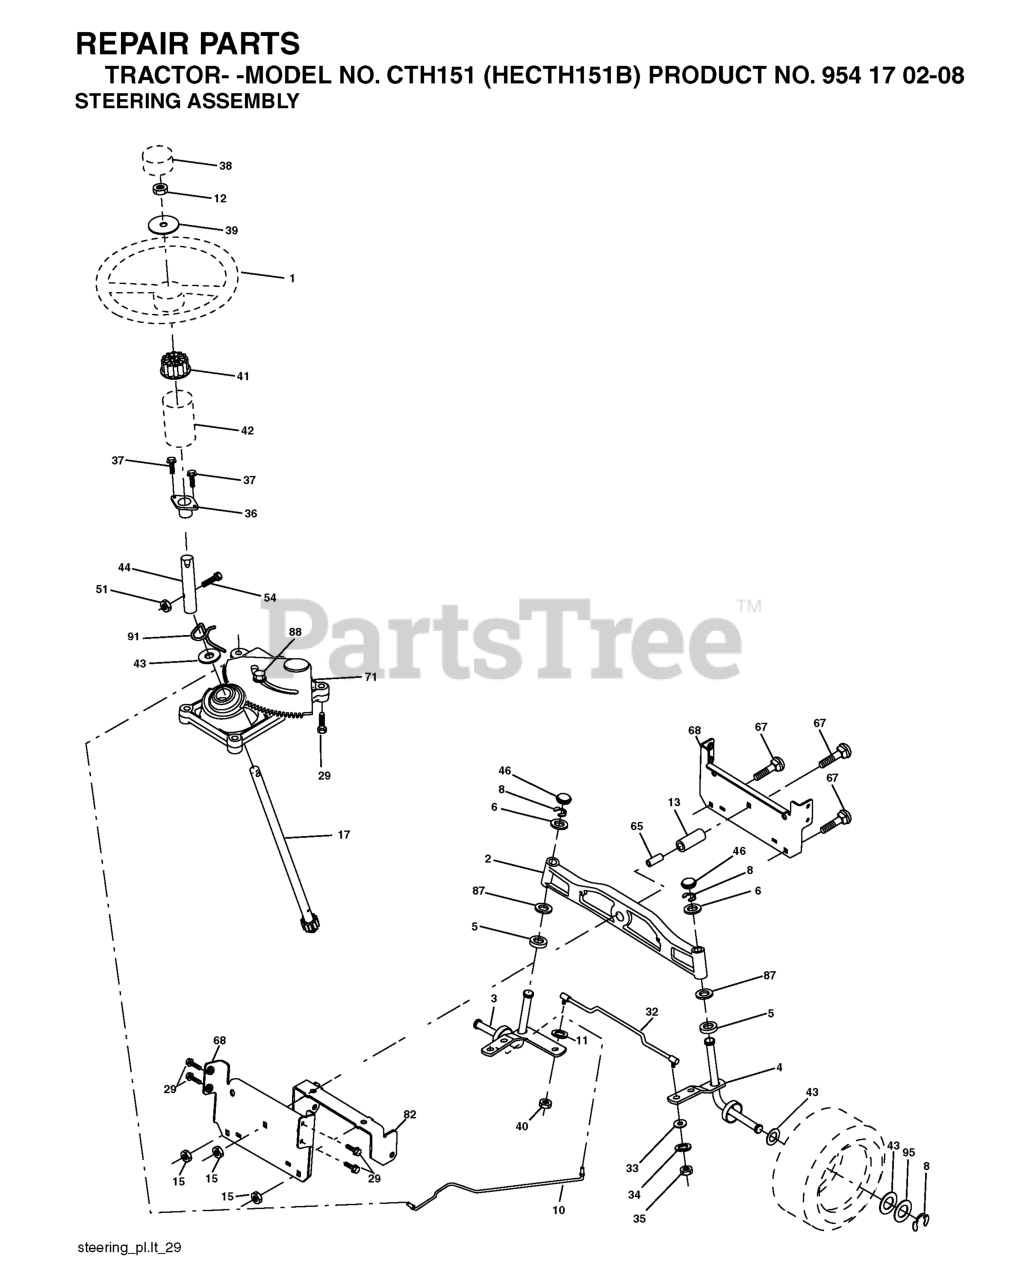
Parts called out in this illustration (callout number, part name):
1	STEERING WHEEL
2	AXLE ASSY FRONT
3	SPINDLE.ASM.LH.15"TIRES
4	SPINDLE.ASM.RH.15"TIRES
5	THRUST WASHER
10	DRAGLINK.15".TIRES.2001
11	WASHER, LOCK 3/8
12	NUT.HEX.1/2-20
13	TUBE, PIVOT AXLE
15	NUT
17	SHAFT ASM, STEERING
29	SCREW, 3/8-16X3/4
32	ROD.ASM.TIE.BALL.JOINT.NOVAN
33	WASHER M
34	WASHER.LOCK.HVY.HLCL.SPR.5/16
35	NUT, CROWNLOCK
36	BUSHING, STEERING
37	SCREW.TT.#10-32X.5.3/8.FLANGE
38	CAP.WHEEL.STEERING.GREY
39	Washer 9/16 ID x 1 1/2 OD 11 Ga. Zin
40	GRIPCO NUT
41	STEERING WHEEL ADAPTOR
42	BOOT STEERING
44	EXT, STEERING SHAFT
46	CAP.SPINDLE.BLACK
51	NUT.CROWNLOCK.1/4-28
54	Bolt Hex 1/4-28 unf x 1-1/4 Gr. 8
65	SPACER BRACE AXLE
67	BOLT CARRIAGE
68	BRACE.AXLE.15"TIRES
71	STEERING ASM
82	BRACKET
87	WASHER, FLAT .781 X 1 1/2"
88	BOLT, SHOULDER 7/16-20
91	CLIP.STEERING
95	WASHER.HARDENED
